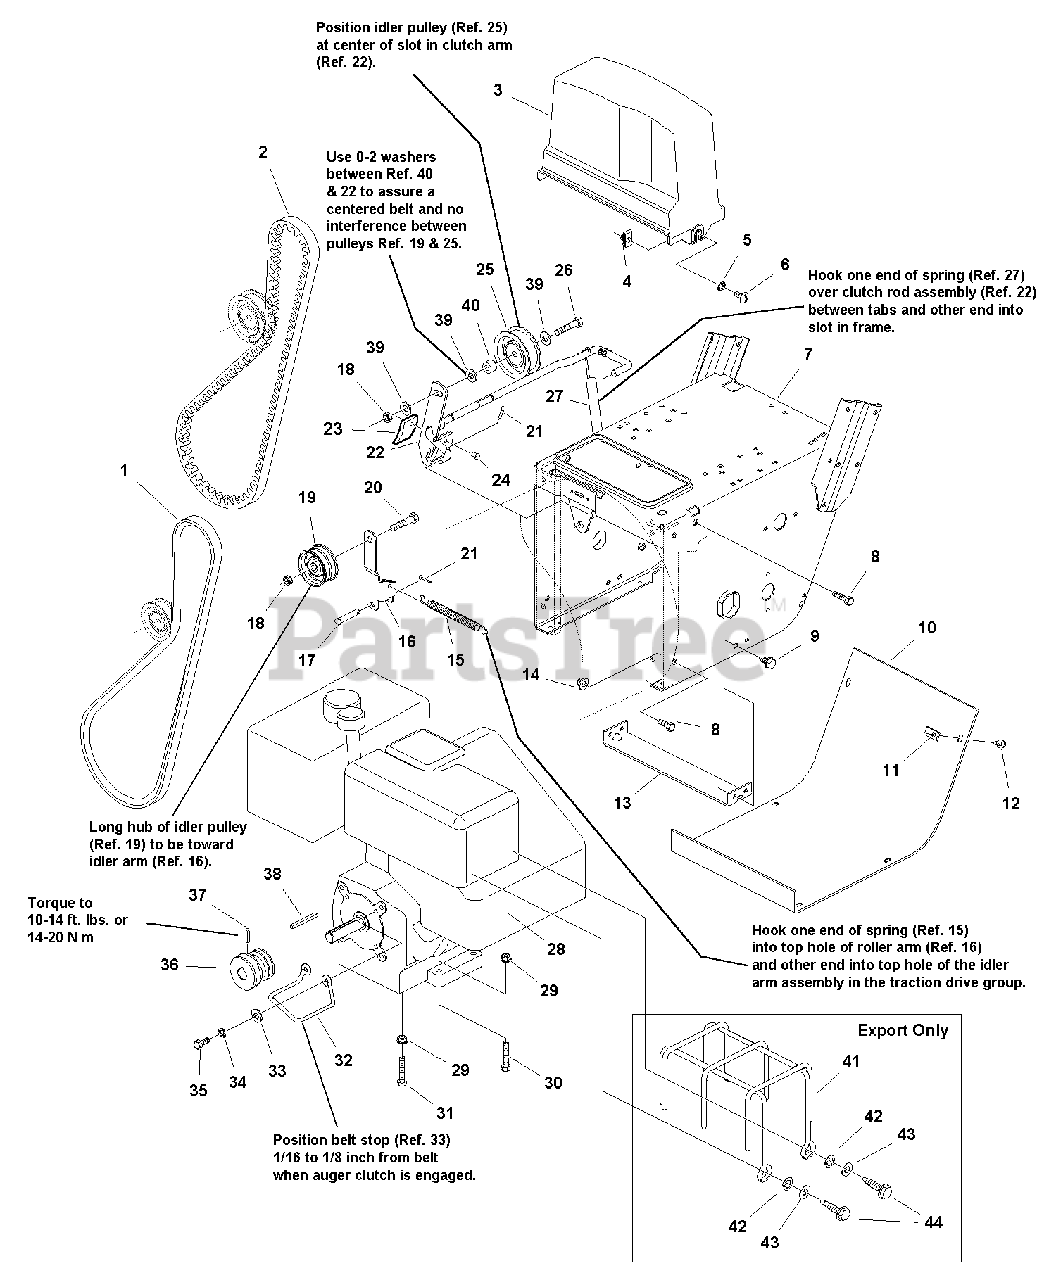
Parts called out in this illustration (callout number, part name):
1	BELT, Traction
2	BELT, Drive Auger
3	GUARD, Belt
4	NUT, Speed, 5/16-18
5	LOCKWASHER, Ext. Tooth, 5/16
6	SCREW, Truss Head, 5/16-18 x 3/4
7	FRAME, Main
8	CAPSCREW, Whizlock, 5/16-18 x 3/4
9	CAPSCREW, Taptite, 5/16-18 x 3/8
10	COVER, Bottom
11	NUT, Speed, 1/4-20
12	CAPSCREW, Taptite,1/4-20 x 1/2
13	SUPPORT, Tie Bar
14	NUT, Hex, Whizlock, 5/16-18
15	SPRING, Idler
16	ARM, Idler, Traction
17	PIN
18	LOCKNUT, Jam, 3/8-16
19	PULLEY, Idler
20	CAPSCREW, Hex Head, 3/8-16 x 1-1/2
21	PlN, Cotter, 1/8 x 3/4
22	CLUTCH ROD & BRAKE ASSEMBLY
26	CAPSCREW, Hex Head, 3/8-16 x 1-3/4
27	SPRING, Extension
29	NUT, Hex, 5/16-18
30	CAPSCREW, Hex Head, 5/16-18 x 1 3/4
31	CAPSCREW, Hex Head 5/16-18 x 2 G5
32	GUIDE, Belt
33	WASHER,11/32 x 3/4
34	LOCKWASHER, 5/16
35	CAPSCREW, Hex Head, 5/16-24 x 3/4
36	PULLEY, Traction
37	SETSCREW, .625 LG
38	KEY, Parallel, 3/16 x 13/16 x 7/8
39	WASHER, Flat,13/32
41	GUARD, Wire Muffler Sheild (Export Only)
42	LOCKWASHER, Spring 3/16 (Export Only)
43	WASHER, Rivet 3/16 (Export Only)
44	CAPSCREW, Hex Washer Head, Self Tap (Export Only)
